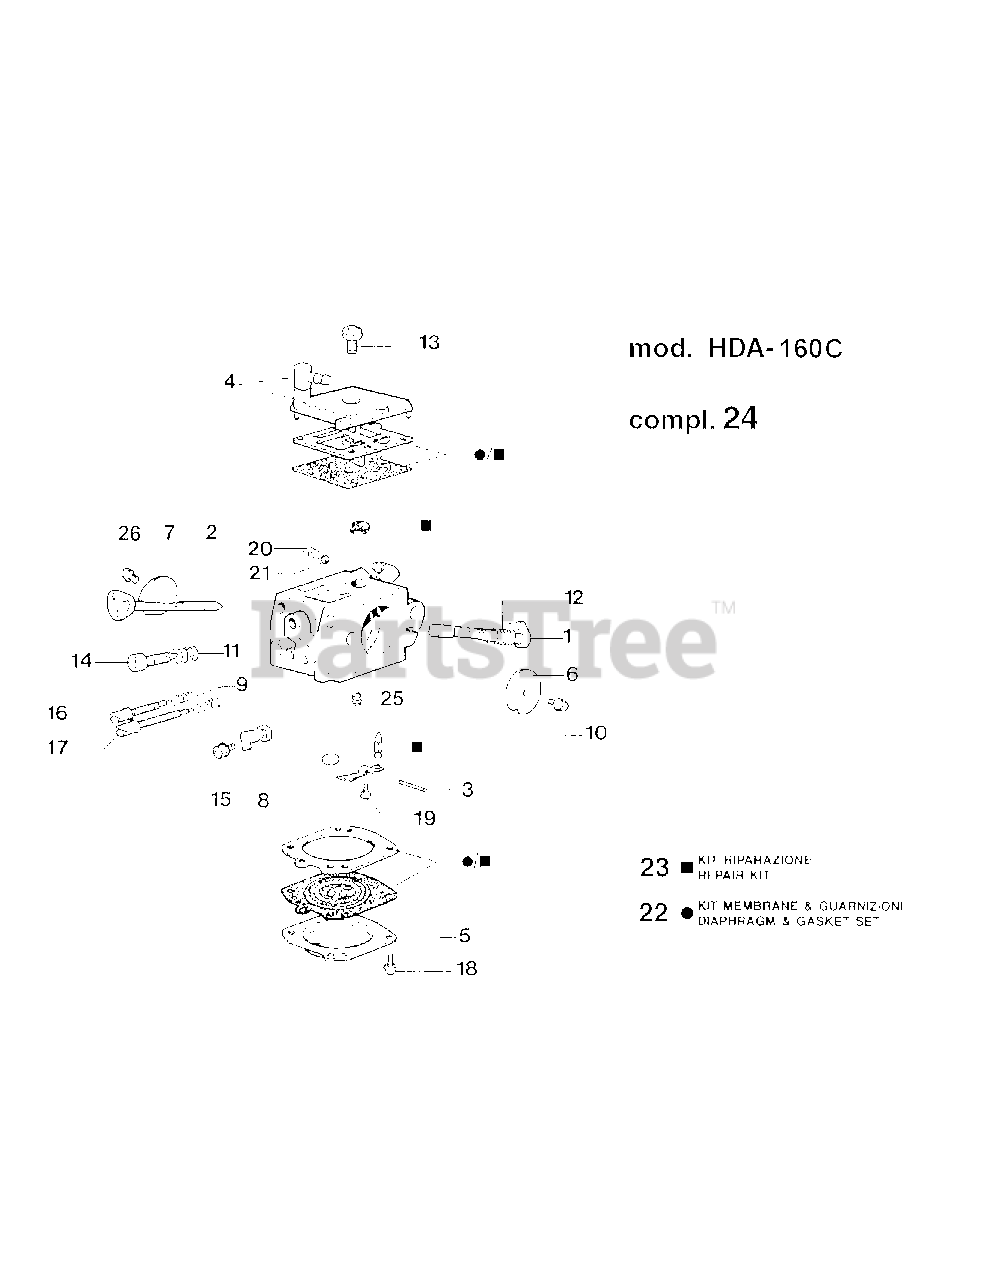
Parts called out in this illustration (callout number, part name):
1	THROTTLE SHAFT
2	STARTER SHAFT
6	THROTTLE VALVE.
7	CHOKE SHUTTER
8	THROTTLE HOLDER
22	GASKET/DIAPH.
24	CARBURETOR
